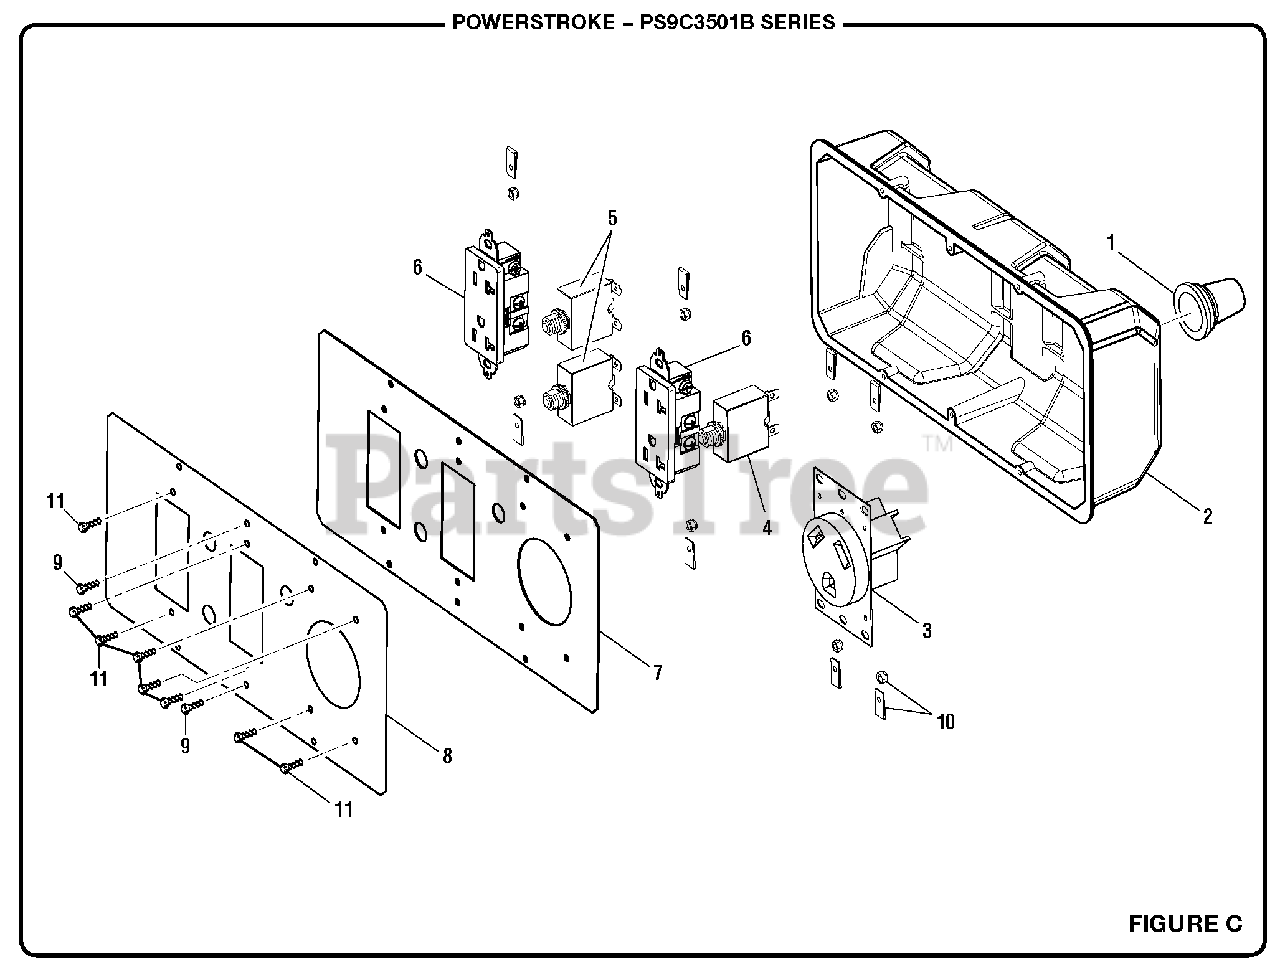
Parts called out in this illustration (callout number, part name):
1	Rubber Boot
2	Rear Control Panel
3	Twist Lock Receptacle (120 Volt, 30 Amp)
4	Circuit Breaker (30 Amp)
5	Circuit Breaker (20 Amp)
6	Duplex Receptacle (120 Volt)
7	Cover Plate
8	Electrical Outlet Label
9	Screw (6-20 x .38 in., Type B)
10	Lock Nut (6-32)
11	Screw (6-32 x 12.7 mm, Pan Hd.)
